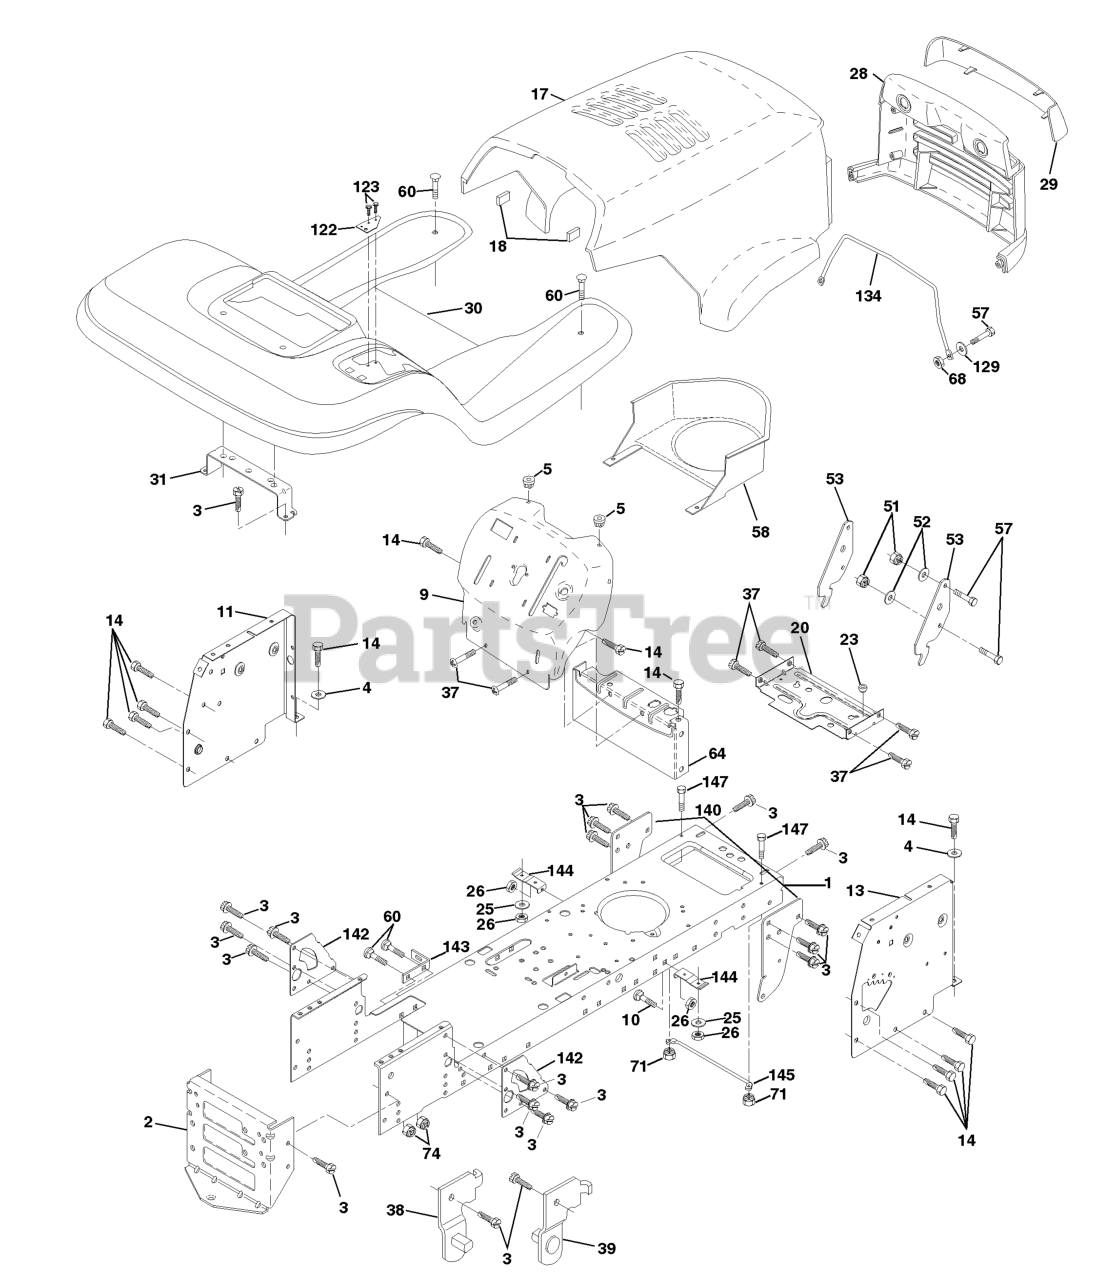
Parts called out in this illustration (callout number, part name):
1	CHASSIS WELDMENT
2	STRETCH DRAWBAR
3	SCREW
4	Washer 13/32 x 3/4 x 16 Ga.
5	BUMPER.RUBBER.HOOD
9	DASH P/L GREY LTH-120
10	BOLT D
11	PANEL DASH LH
13	PANEL DASH RH
14	SCREW LT
17	HOOD - LT/YT
18	BUMPER HOOD T
20	PLATE MTG
23	BUSHING.SNAP.NYL.BLK.
25	WASHER
26	NUT
28	GRILLE LT/PL HUSQVARNA
29	LENS LT/PL HUSQVARNA
30	FENDER FOOTREST
31	BRACKET.SUPPORT.FENDER
37	Screw Thdrol 6/16-18 x 1/2 TYT
38	BRACKET LH PIVOT
39	BRACKET RH PIVOT
51	LOCKNUT.NYLOC.1/4-20
52	WASHER
53	BRACKET PNT PICK OFF LT/PL
57	BOLT
58	AIR DUCT P/L/LT
60	Bolt Rdhd Sqnk 3/8-16unc x 3/4
64	DASH LOWER
68	NUT
71	NUT.CROWNLOCK.1/4
122	BRACKET SHIFT STLT
123	SCREW.TT.#10-32X.5.3/8.FLANGE
129	WASHER
134	ROD SUPPORT HOOD LT/PL HUS.
140	BRACKET SUSPENSION FRONT
142	PLATE REINFORCEMENT
143	BRACKET, SWAY BAR
144	BRACKET FOOTREST
145	ROD PIVOT CHASSIS/HOOD
147	BOLT.HEX.1/4.X.3/4.DICHROMATE
